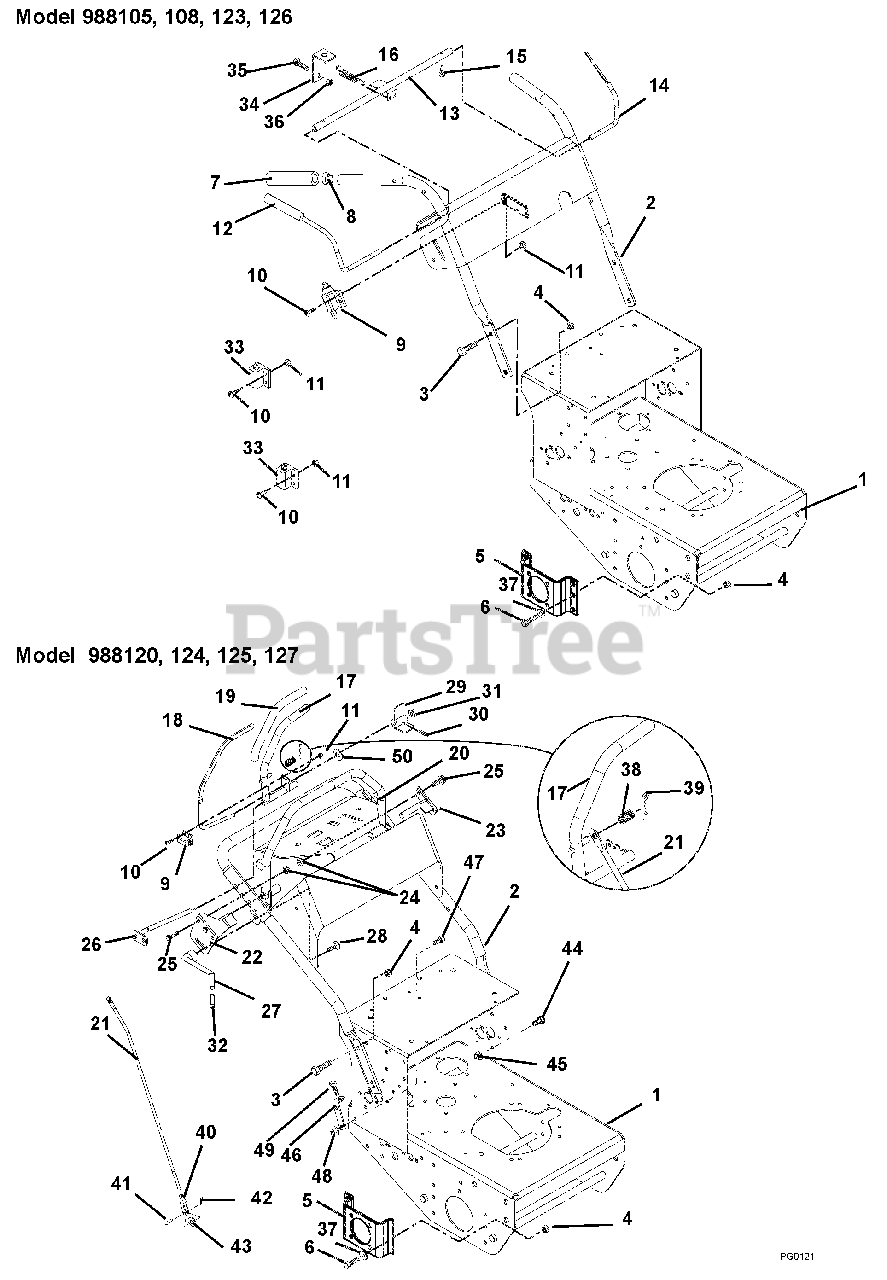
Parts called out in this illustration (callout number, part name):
1	Kit, Frame with Decals
2	Kit, Handlebar with Decals HR15 (105)
3	Bolt, Hex .38-16 x 1.00 Grade 5
4	Nut, Locking-Nylon .38-16
5	Bracket, Wheel Motor Left Hand (105, 108, 120, 124, 125)
6	Bolt, Hex .38-16 x 1.00 Grade 5
7	Grip, Handlebar (105, 108, 123, 126)
8	Caplug, Handlebar (105, 108, 123, 126)
9	Switch, Interlock (105, 108, 123, 126)
10	Screw, Machine 10-24 x .75 Hex Washer Head (105, 108, 213, 126)
11	Nut, Locking-Nylon 10-24 with Insert (105, 108, 123, 126)
12	Lever, Right Hand-Operator Presence (105, 108, 123, 126)
13	Weldment, Pivot Tube (105, 108, 123, 126)
14	Lever, Left Hand-Operator Presence (105, 108, 123, 126)
15	Screw, Tapping 8-32 x .50 Hex Washer Head (105, 108, 123, 126)
16	Spring, Tension .047 x .438 x 1.45 (105, 108, 123, 126)
17	Weldment, Lever-Right Hand Speed Control (120, 124, 125, 127)
18	Lever, Operator Presence (120, 124, 125, 127)
19	Grip, Handlebar (120, 124, 125, 127)
20	Weldment, Speed Control Stop (120, 124, 125, 127)
21	Rod, Steering (120, 124, 125, 127)
22	Weldment, Control Stop Limiter-Right Hand (120, 124, 125, 127)
23	Weldment, Control Stop Limiter-Left Hand (120, 124, 125, 127)
24	Nut, Locking-Top-Flange .31-18 (120, 124, 125, 127)
25	Bolt, Hex .31-18 x 1.75 Grade 5 (120, 124, 125, 127)
26	Weldment, Speed Control Pivot- Right Hand (120, 124, 125, 127)
27	Lever, Control Stop Lock (120, 124, 125, 127)
28	Bolt, Round Head Square Neck .38-16 x .75 Grade 2 (120, 124, 125, 127)
29	Actuator, Switch (120, 124, 125, 127)
30	Pin, Roll .125 x .75 (120, 124, 125, 127)
31	Nut, Push .312 (120, 124, 125, 127)
32	Grip, Hand Clutch Lever (120, 124, 125, 127)
33	Switch- Double Pole N.O./N.O. (105, 108, 123, 126)
34	Bracket, Brake Link (105, 108, 123, 126)
35	Bolt, Hex .25-20 x .75 Grade 5 (105, 108, 123, 126)
36	Nut, Locking Nylon .25-20 (105, 108, 123, 126)
37	Washer, Flat Steel .406 x .812 x .065 (105, 108, 123, 126)
38	Spring, Compression .045 x .60 x .75 (120, 124, 125, 127)
39	Pin, Hair Internal .08 x .18 x 1.18 (120, 124, 125, 127)
40	Yoke, .312-24 x 2.25 (120, 124, 125, 127)
41	Pin, Clevis .31 x .937 (120, 124, 125, 127)
42	Pin, Hair, Endries #25 (120, 124, 125, 127)
43	Washer, Flat-Steel .38 x .87 x .179 (120, 124, 125, 127)
44	Bolt, Hex .31-18 x 1.00 Grade 5 (120, 124, 125, 127)
45	Nut, Spin Lock-Flange .312-18 (120, 124, 125, 127)
46	Weldment- Reverse Adjustment Bracket (120, 124, 125, 127)
47	Bolt, Hex .38-16 x .75 Grade 5 (120, 124, 125, 127)
48	Nut, Locking-Top-Flange .38-16 (120, 124, 125, 127)
49	Bolt, Hex .31-18 x 1.25 Grade 5 (120, 124, 125, 127)
50	Washer, Wave (120, 124, 125, 127)
